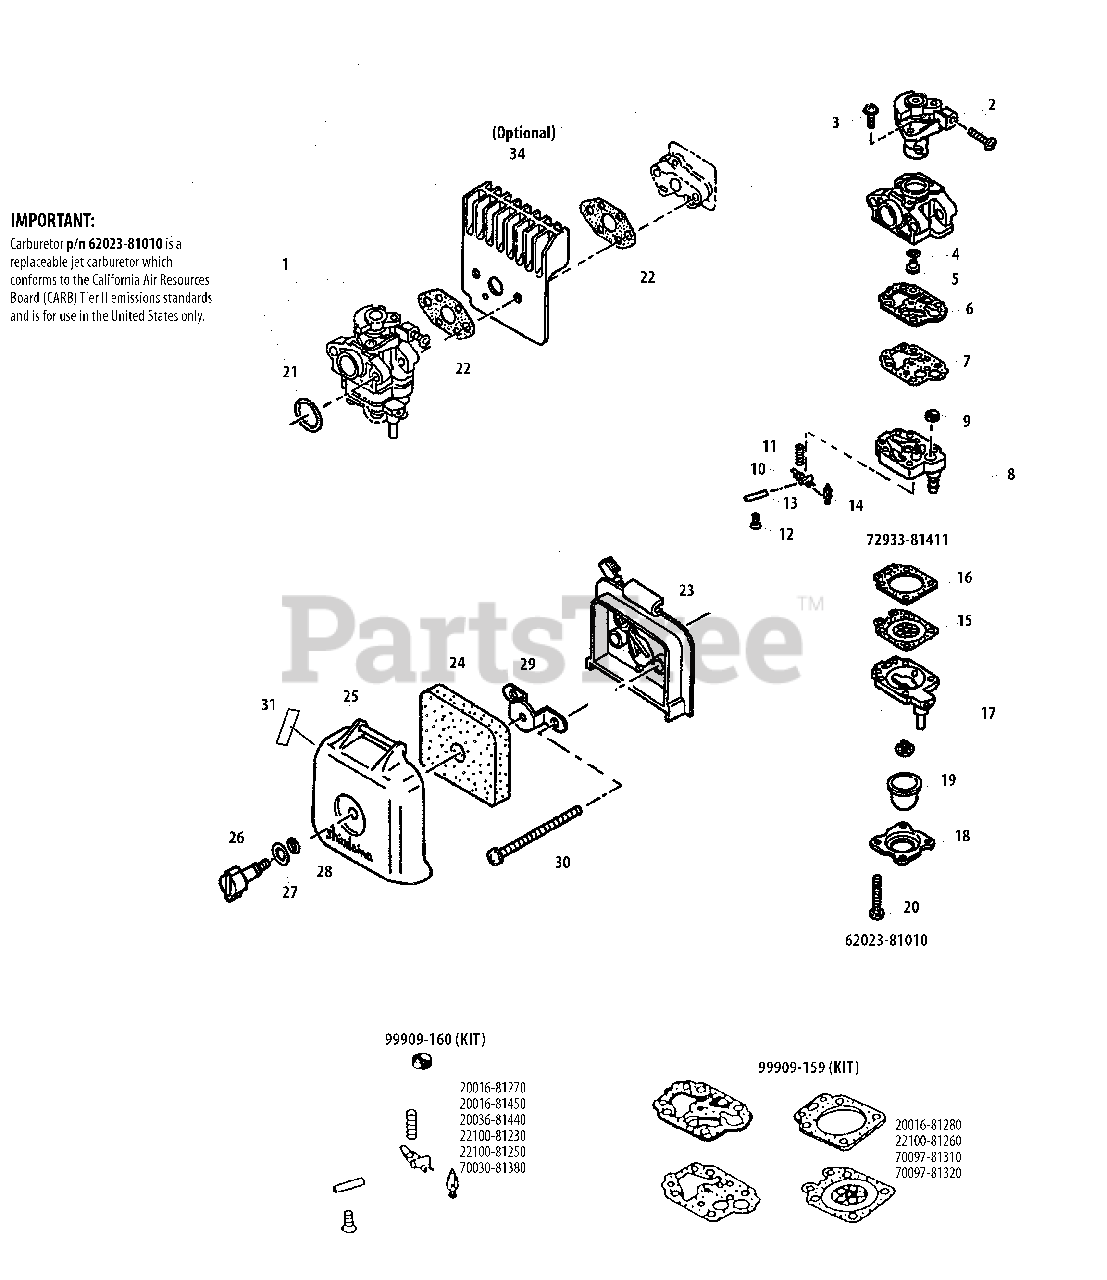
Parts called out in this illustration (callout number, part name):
1	CARBURETOR
2	VALVE, THROTTLE
3	SCREW
4	O-RING
5	JET, MAIN
6	GASKET, PUMP
7	DIAPHRAGM, PUMP
8	BASE, PURGE
9	STRAINER
10	VALVE, INLET NEEDLE
11	SPRING, METERING LEVER
12	SCREW, METERING LEVER PIN
13	PIN, METERING LEVER
14	LEVER, METERING
15	DIAPHRAGM, METERING
16	GASKET, METERING
17	BASE, PURGE
18	RETAINER, PURGE BULB
19	BULB, PURGE
20	SCREW, PUMP COVER
21	O-RING - 15
22	GASKET
23	CASE, AIR FILTER
24	FILTER, AIR - FOAM
25	COVER, AIR FILTER
26	THUMBSCREW
27	O-RING
28	WASHER - CONICAL
29	PLATE, PREVENT
30	SCREW - 5X67
31	LABEL - CHOKE
34	DEFLECTOR, HEAT
99909-159	DIAPHRAGM/GASKET KIT
99909-160	REPAIR KIT
